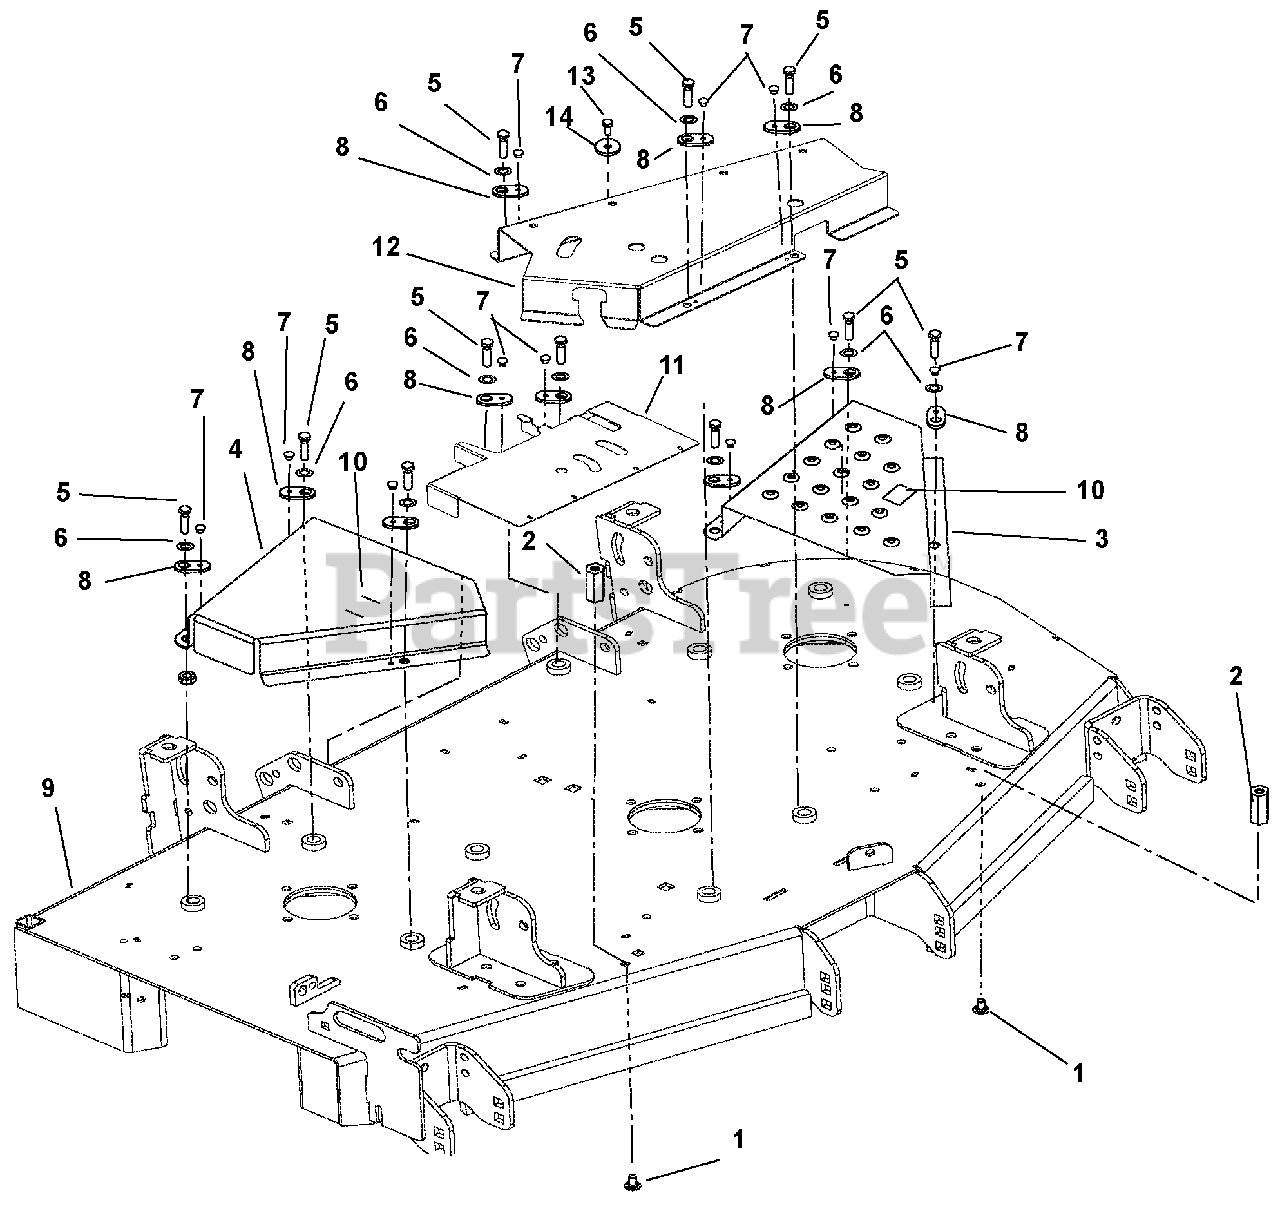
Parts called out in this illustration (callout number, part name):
1	Bolt, Round Head Square Neck .31 - 18 x .75
2	Nut, Coupling .31 - 18 x 3.00
3	Cover, Left Hand Belt, CE
4	Cover, Right Hand CE Belt
5	Bolt, Hex .38-16 x 1.25
6	Washer, Locking, EXT.391 x .682 x .036
7	Rivet, Pop .187
8	Keeper, Bolt
9	Weldment, 48" PT100 Side Dis Deck, CE
10	Decal, Pinch Point
11	Shield, Belt, Rear
12	Shield, Belt, Front
13	Bolt, Hex .25-20 x .75 Grade 5 YZ
14	Washer, Flat Steel .281 x .62 x .065 YZ
